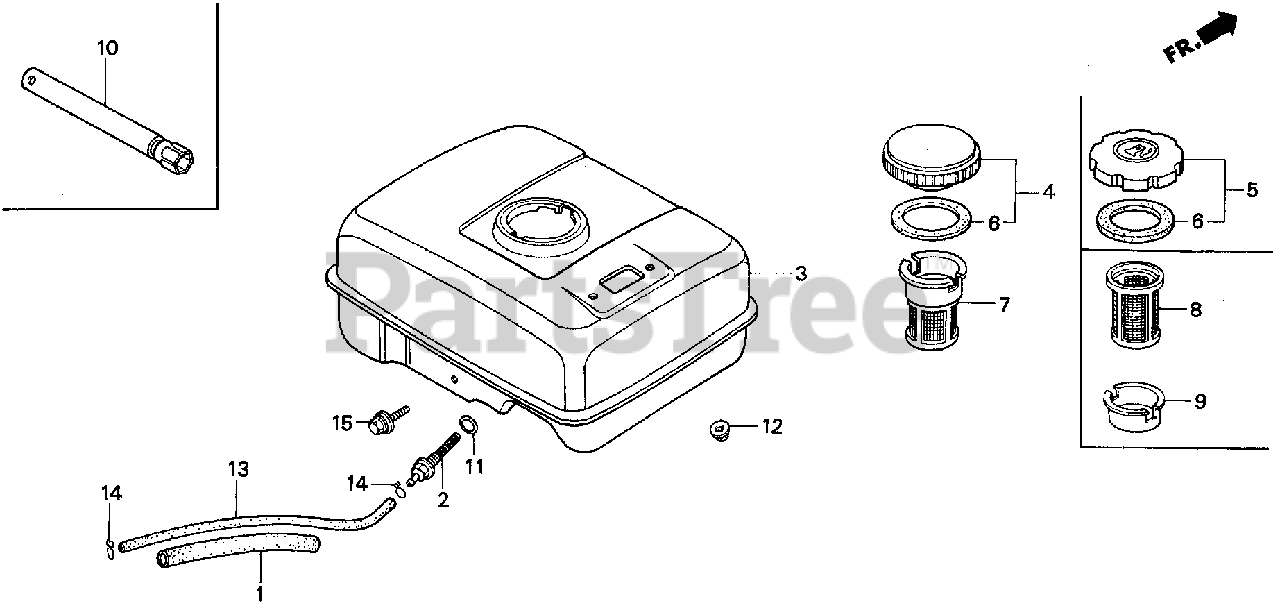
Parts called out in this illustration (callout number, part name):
1	RUBBER, SUPPORTER (107MM)
2	JOINT, FUEL TANK
3	TANK, FUEL *R8* (BRIGHT RED)
3	TANK, FUEL *NH1* (BLACK)
4	CAP, FUEL FILLER
5	CAP, FUEL FILLER
6	GASKET, FUEL FILLER CAP
11	O-RING (13.5X1.5) (ARAI)
12	NUT, FLANGE (6MM)
13	BULK HOSE, FUEL (4.5X3000) (4.5X140)
14	CLIP, TUBE (B8)
15	BOLT, FLANGE (6X25)
